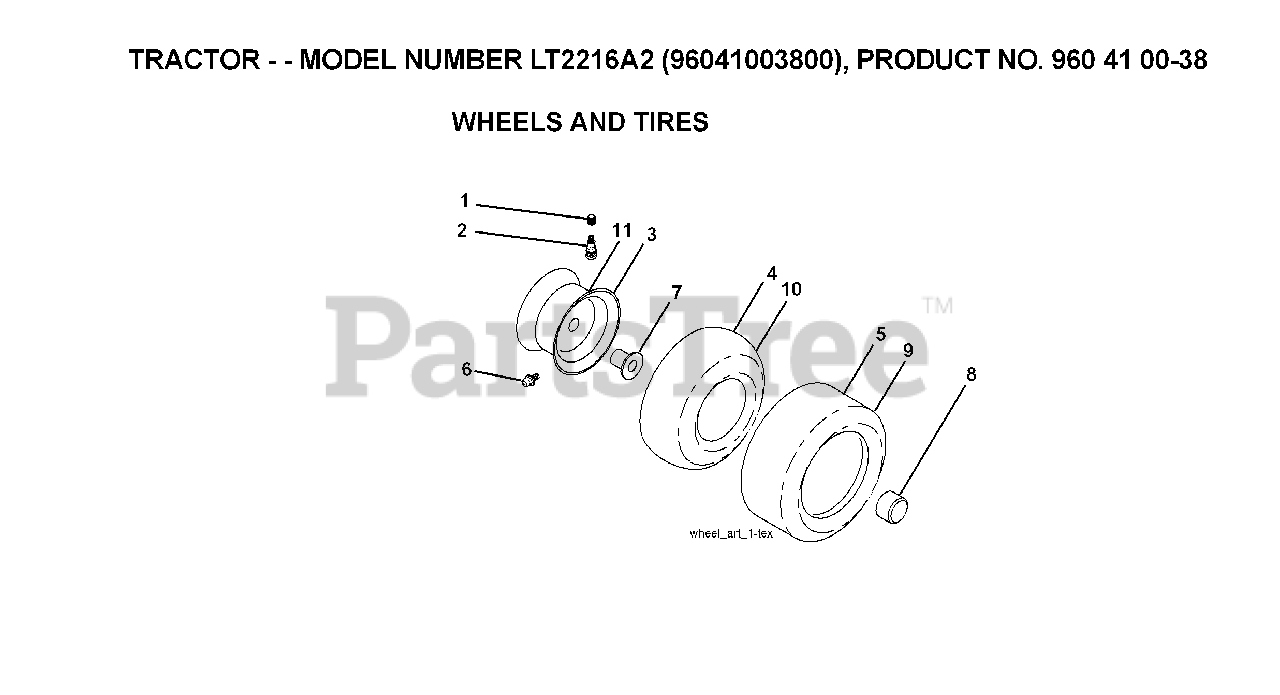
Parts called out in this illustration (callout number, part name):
1	VALVE CAP
2	VALVE STEM LT
3	RIM ASM 6" FRONT SILVER
4	TUBE.5.3/4.5/6
5	TIRE HEAVY DUTY
6	FITTING LT
7	BEARING T
8	CAP, AXLE BLK
9	TIRE.TS.20X10-8
10	TUBE
11	RIM ASM 8" REAR SILVER
